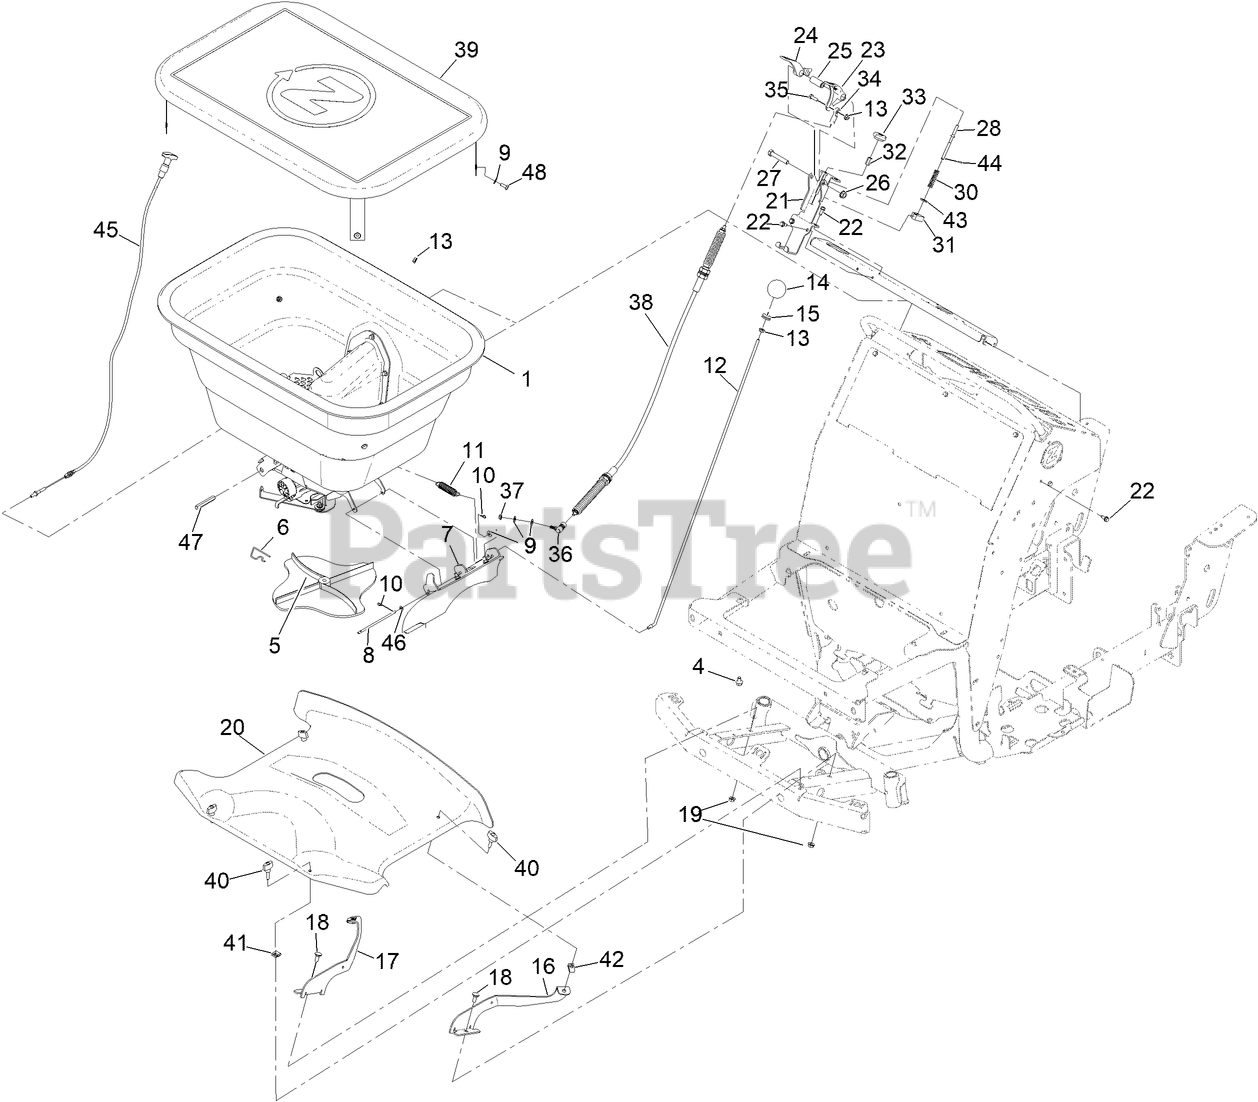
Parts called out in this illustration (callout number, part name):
1	SPREADER HOPPER ASM
4	SCREW-HHF
5	SPINNER-SPREADER
6	CLIP-SPINNER
7	SIDE DEFLECTOR ASM
8	PIN-DEFLECTOR
9	WASHER-FLAT
10	PIN-COTTER, HAIR
11	SPRING-EXTENSION
12	ROD-CONTROL, DEFLECTOR
13	NUT-HF
14	KNOB-RATE, FLOW
15	GROMMET
16	BRACKET-COVER, FRONT (LH)
17	BRACKET-COVER, FRONT (RH)
18	SCREW-CARR
19	NUT-HF
20	COVER-FRONT, SPREADER/SPRAYER
21	MOUNT-HANDLE
22	SCREW-HWH
23	LEVER-SPREAD, WIDE
24	LEVER-SPREAD, NARROW
25	SPACER
26	NUT-HF
27	SCREW-HH
28	LINK-ADJUST, NARROW
30	SPRING-COMPRESSION, BAIL
31	STOP-SPREAD, NARROW
32	NUT-COUPLER
34	ROD END-BALL JOINT
35	SCREW-HH
36	BALL-JOINT
37	NUT-HEX, NI
39	COVER-HOPPER
40	KNOB-T
41	NUT-RETAINER, U STYLE
42	NUT-RETAINER
43	WASHER-FLAT
44	PIN-COTTER
45	CABLE-CONTROL, TURN LOCK
46	WASHER-FLAT
47	POST-HEX, DIFFUSER GUIDE
48	SCREW-HH
